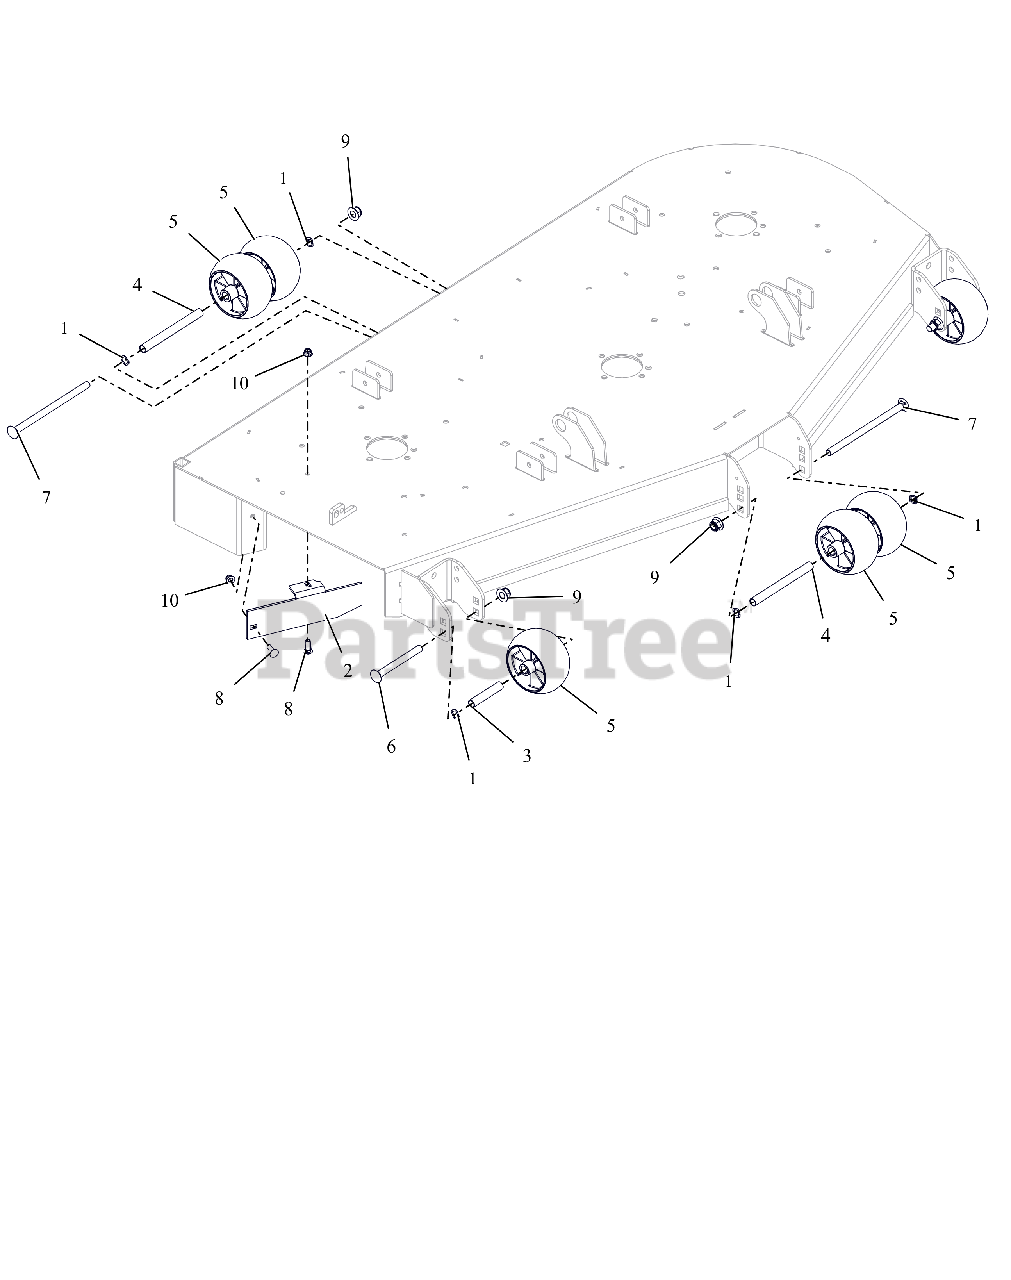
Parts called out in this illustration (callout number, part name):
1	WAVE WASHER .531X.781X.125FH
2	BAFFLE, 60" DISCHARGE
3	SPACER, .510X.625X3.35
4	SPACER, .510X.625X6.50
5	ANTI-SCALP WHEEL - 5X3 CTR
6	BLT-RDHDSQNK .50-13X5.00 GR5YZ
7	@BLT-RDHDSQNK .50-13X8.50 G5YZ
8	@BLT-RDHDSQNK .31-18X1.00 G5YZ
9	@NUT-LK-NYL-FLG .50-13 YWZC
10	@NUT-LK-NYL-FLG .31-18 YWZC
